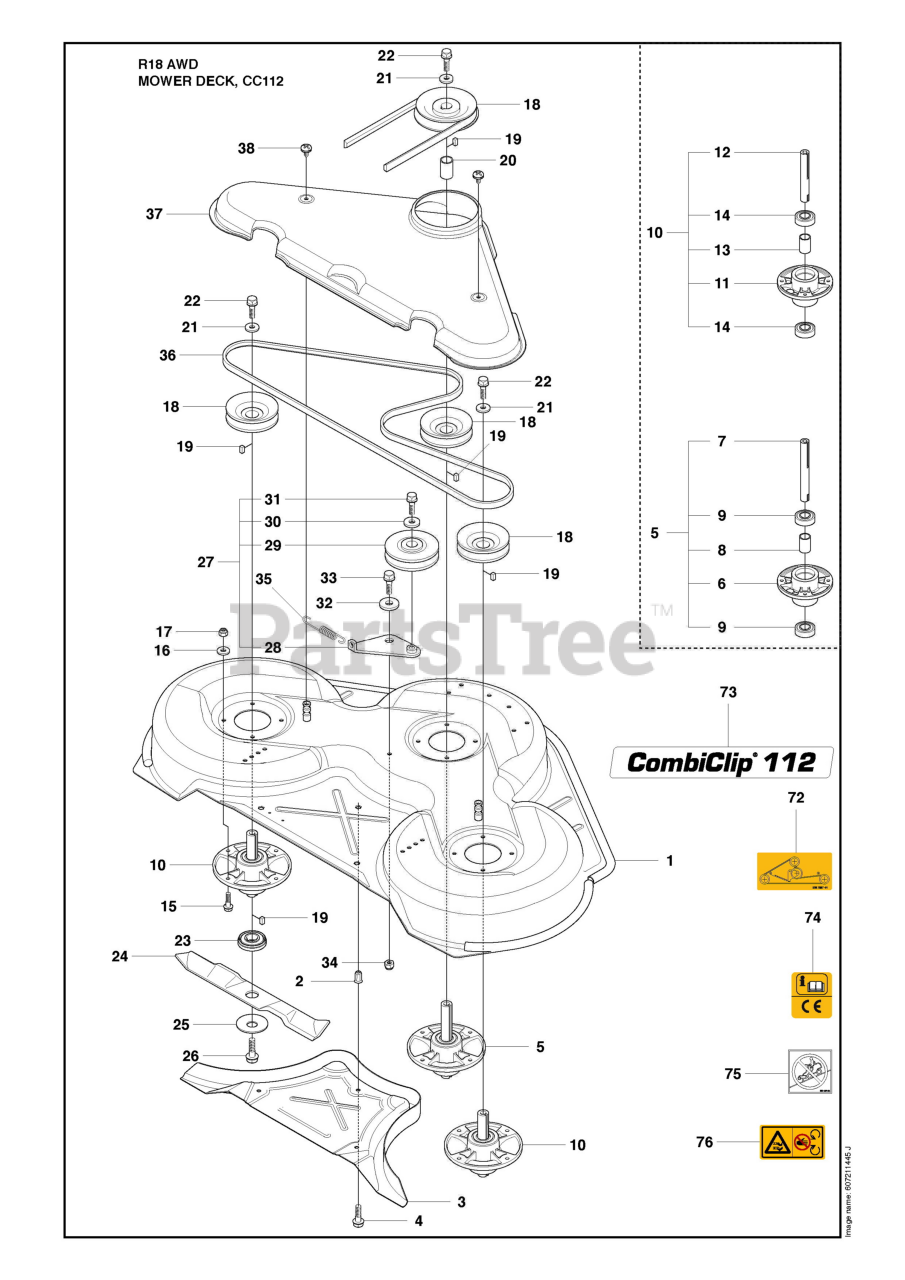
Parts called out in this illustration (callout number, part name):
1	CUTTING DECK
5	SPINDLE ASSY
6	BEARING HOUSING
10	RP SPINDLE ASSY
11	BEARING HOUSING
16	WASHER BRB 8.4X17
17	LOCKNUT M8
24	BLADE
25	WASHER
27	BELT TENSIONER ASSY
28	BELT TENSIONING ARM
32	WASHER
34	LOCKNUT M8
36	BELT
37	BELT COVER
42	LOCKNUT M8
48	LOCKNUT M8
49	PARALLELL ROD ASSY
50	PARALLEL ROD
51	RETAINER
53	DECK FRAME
55	PIVOT WHEEL ASSY
57	DECK ROLLER, FRONT
61	NUT
62	CLIP GRAY
66	Screw
67	LOCKNUT M8
68	DECK ATTACHMENT
70	Screw
